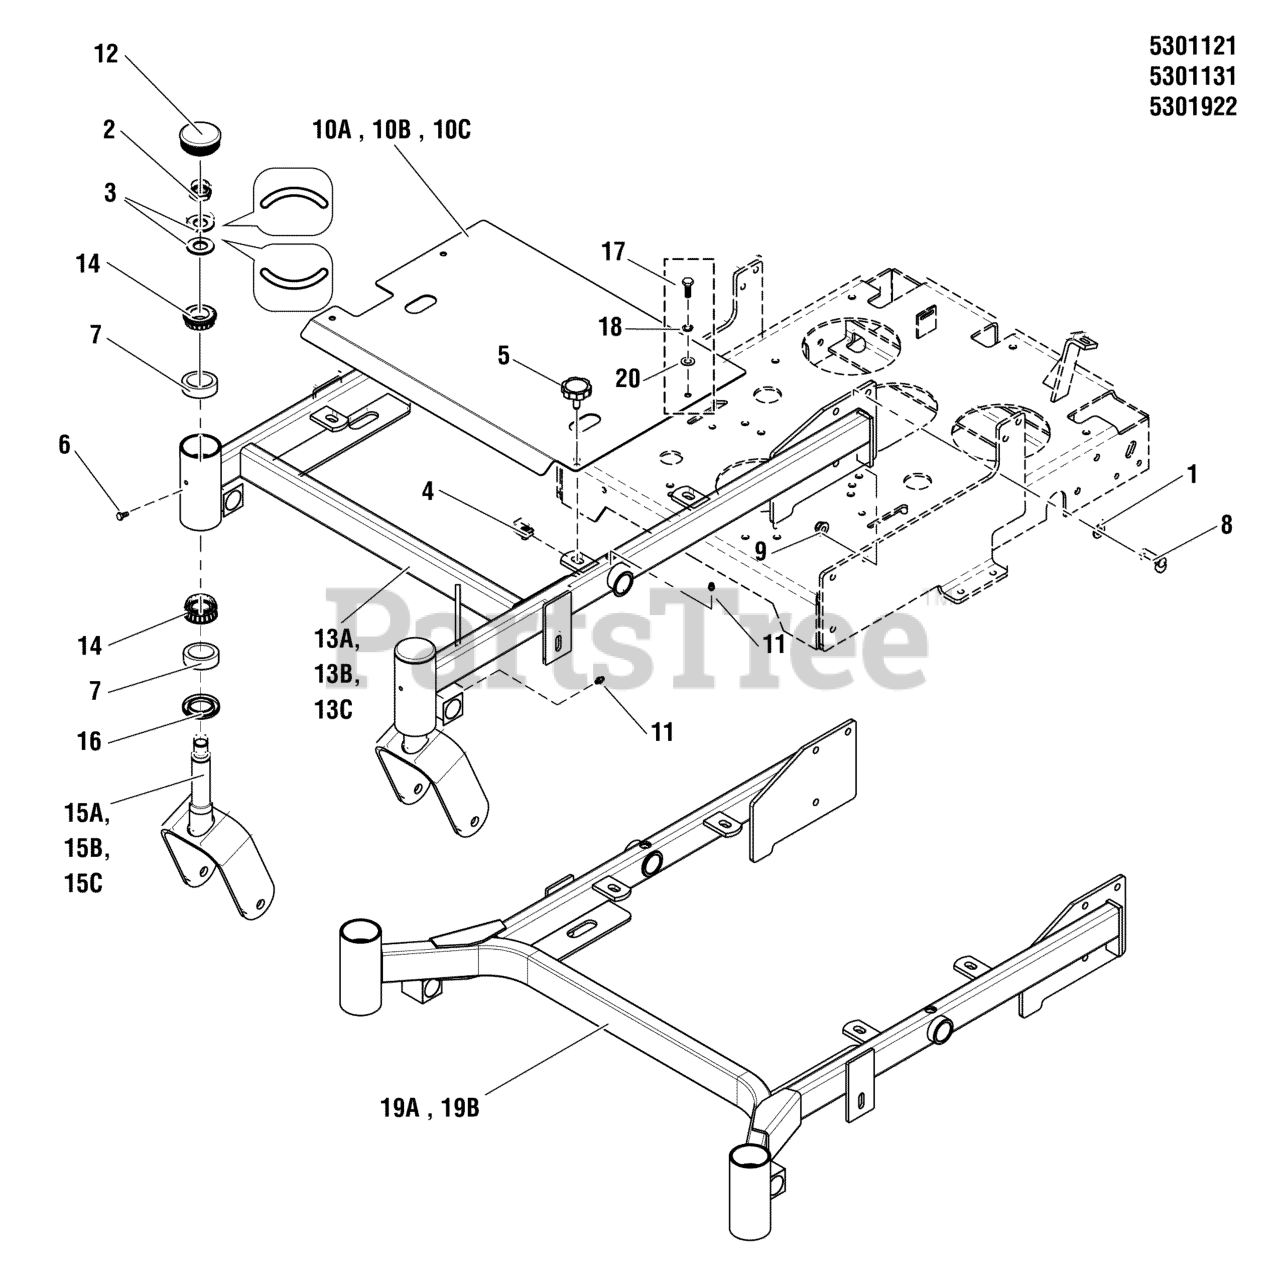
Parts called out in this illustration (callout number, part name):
1	WASHER, 1/2 SAE
2	NUT, 3/4-16, HEX JAM NYLON LOCK
3	WASHER, BELLEVILLE - 1.500 X .755
4	BODY CLIP, 5/16-18 -1/4 MATERIAL
5	KNOB, 5/16-18 X 1.00, ROSETTE, BLK
6	BOLT, 1/4-28 X 1/2, GD5 YZ
7	CUP, BEARING (SV)
8	BOLT, 1/2-13 X 1-1/2 GD5 CZ
9	NUT, Hex Flange, Nylock, 1/2-13
11	GREASE FITTING, 1/4-28 STRAIGHT
12	CAP, GREASE, LOW PROFILE
14	BEARING, TAPERED ROLLER, 1"
16	SEAL, GREASE
17	BOLT, 5/16-18 X 1 GD5 YZ
18	WASHER, 5/16 LOCK CZ
20	WASHER, 5/16" SAE
